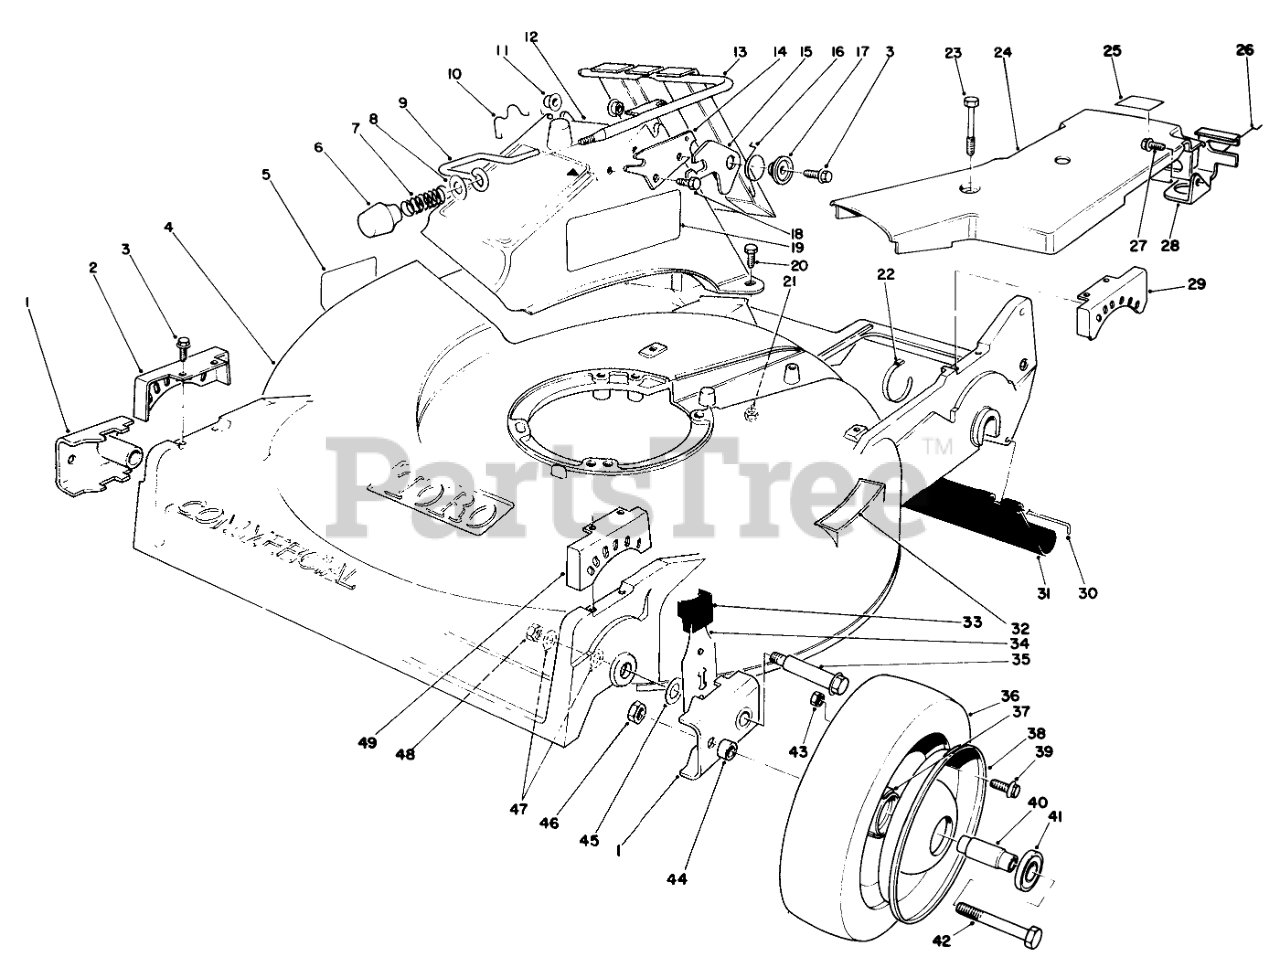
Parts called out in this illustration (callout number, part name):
1	ARM-PIVOT, FRONT
2	QUADRANT-FRONT, RH
3	SCREW-HWHTF
4	Housing-Commercial (Incl. Ref. #5 & 32)
5	DECAL-DANGER
7	COMPRESSION SPRING
8	WASHER-FLAT
9	DOOR LATCH
10	DOOR RETAINER
11	BUSHING-NYLON
12	DISCHARGE CHUTE B
13	DOOR & HANDLE WA
14	DOOR LATCH PLATE
15	SAFETY LATCH
16	TORSION SPRING
17	DOOR SPACER
18	SCREW-HWH
19	DECAL SAF INST
20	SCREW-HH
21	NUT-LOCK, NI
22	TIE-CABLE
23	SCREW-HHFTF
24	Decal-Hot
25	LABEL-GREASE
26	RETAINER-CABLE
27	SCREW-HWHTF
28	Bracket-Traction Adj.
29	QUADRANT-REAR, LH
30	ROD-SHIELD
31	SHIELD-TRAILING
32	STEP PAD DECAL
33	KNOB-ARM
34	Spring Arm Assembly Front
35	WHEEL BOLT
37	HUB-BEARING
38	Wheel-Half
39	SCREW-HHF
40	SPACER-BEARING
41	BEARING-WHEEL
42	SCREW-HH
43	NUT-LOCK, NI
44	SPACER-WHEEL
45	WASHER-THRUST
46	NUT-LOCK, CONE
47	WASHER
48	Nut
49	QUADRANT-FRONT, LH
